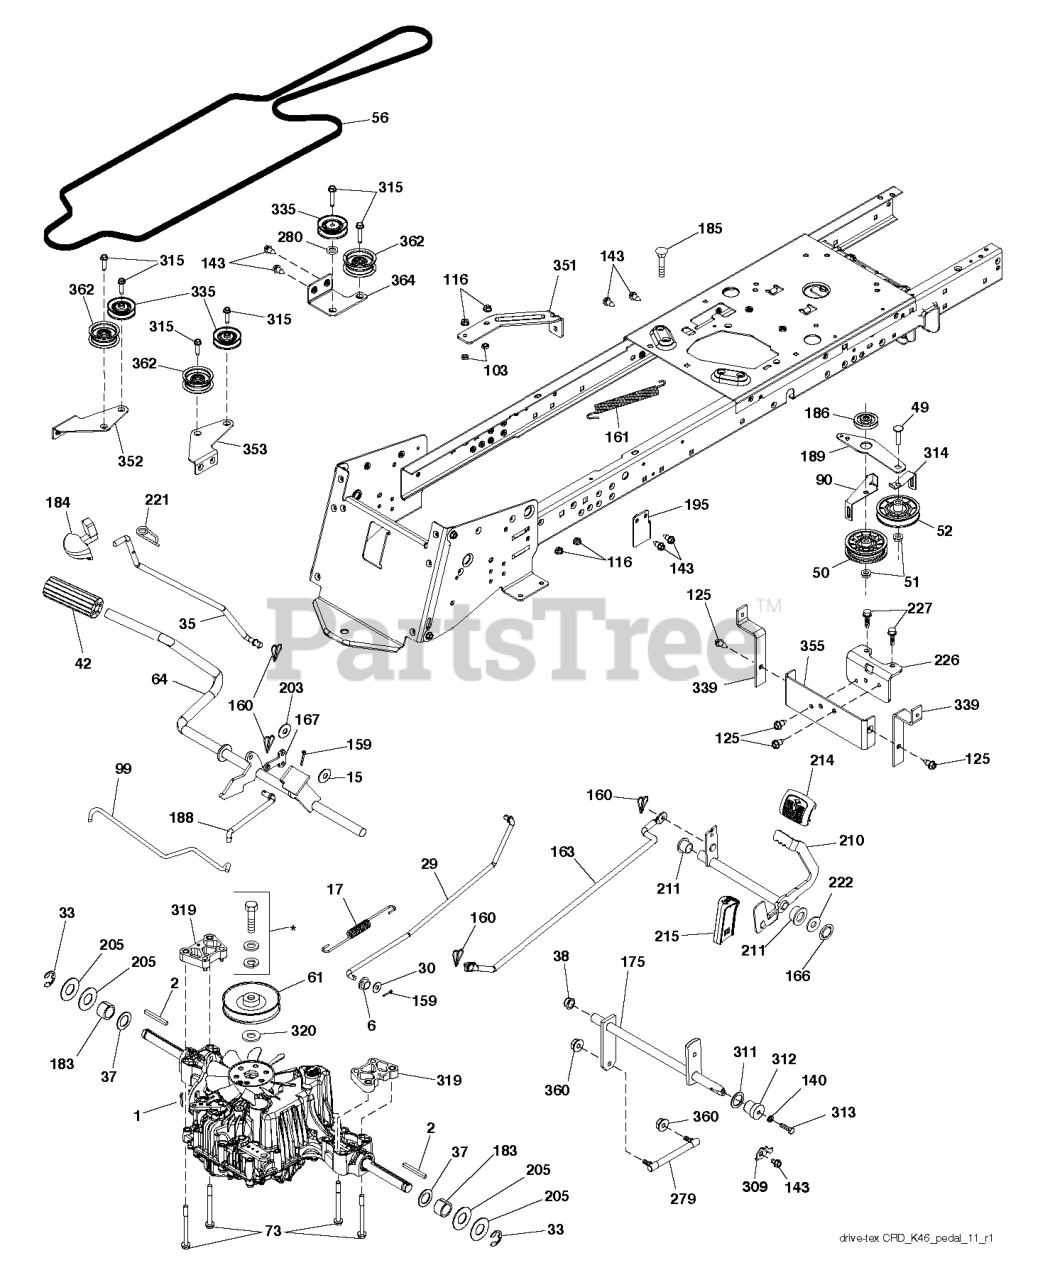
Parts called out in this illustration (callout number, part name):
2	SQUARE KEY
6	BUSHING.SNAP.NYL.BLK.
15	WASHER
17	SPRING
29	ROD
35	ROD.CNTRL.PARK.PREDATOR.LT.TEX
38	NYLINER SNAP 5/8" ID
42	PEDAL COVER T
48	BOLT.3/8-16X1.50
50	IDLER.FLAT.2.25.INCH
51	NUT LOCK FLG 3/8-16 UNC
52	PULLEY.V-IDLER.
56	V BELT DELV 113 K46 CRD
61	PULLEY
64	SHAFT.ASM.PEDAL.BRK.CNTR
73	BOLT.FLANGED
90	BRACKET KEEPER BELT CLUTCHING
93	LINK
99	ROD
103	JAM NUT TI
116	NUT LOCK HEX FLANGE 5/16-18
125	SCREW
140	LOCKWASHER
143	SCREW LT
159	COTTER PIN
160	RETAINER CLIP
161	SPRING, RETURN LT
163	ROD
166	NUT.PUSH.625
167	LATCH.BRAKE.SPRING
175	SHAFT SUBASM.SHAFT.CROSS.SHIFT
183	SPACER AXLE
184	HANDLE.PARKING.BRK.PRED.LT.RED
186	SPACER.RETAINER
187	WASHER 12/32X2X10GA
188	RP.LINK.CLUTCH.GROUND.DRIVE
189	BELLCRANK BELLCRANK GROUNDDRI
201	BOLT SHOULDER 5/16-18 UNC
203	WASHER
210	ROCKER.ASM.PEDAL.CONTR
211	BEARING.NYLON
214	PEDAL.FORWARD.PAD.TEX
215	PEDAL RUBBER REVERSE
221	RETAINER.SPRING.CLIP.H
222	WASHER 21/32 X 1-1/4 X 10 GA.
226	BRACKET.MOUNT.TORQUE.K46.TLT
227	SCREW.THDROL.5/16-18X3/4.TTY
309	PLATE.FASTENING.CROSS.SHAFT
311	WASHER NYL
312	HUB.TAPERED.ROUND.CRD
313	BOLT
314	RETAIN BELT
315	BOLT.5/16-18X1.25
319	SPACER SPACER TRANSAXLE TEX C
320	WASHER.SPACER.MANDREL
321	IDLER PULLEY
326	BOLT CARRIAGE
339	STRAP STRAP TORQUE K46 CRD TE
351	BRACKET BRACKET DECK SWAY
352	BRACKET BRACKET.IDLER
353	BRACKET
355	STRAP STRAP TORQUE K46 CRD TEX
